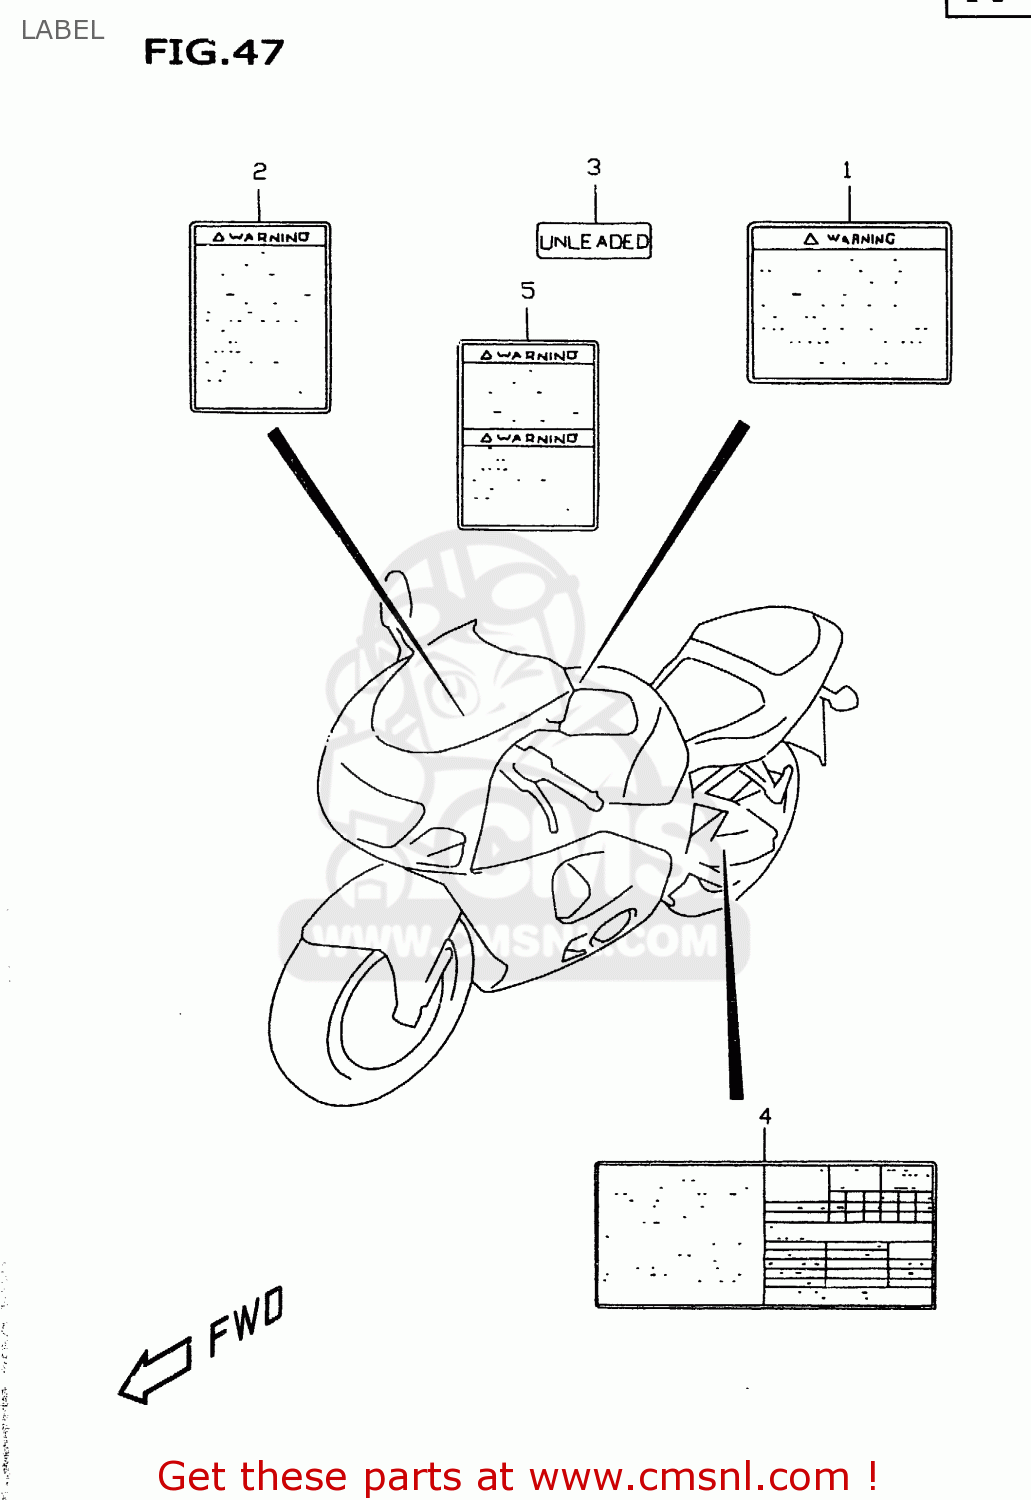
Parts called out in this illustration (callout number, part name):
1	LABEL,WARNING
2	LABEL (WARNING SCREEN)
3	LABEL,CAUTION
4	LABEL,TIRE INFORMATION
5	LABEL,WARNING STEERING
6	MANUAL, OWNER'S
